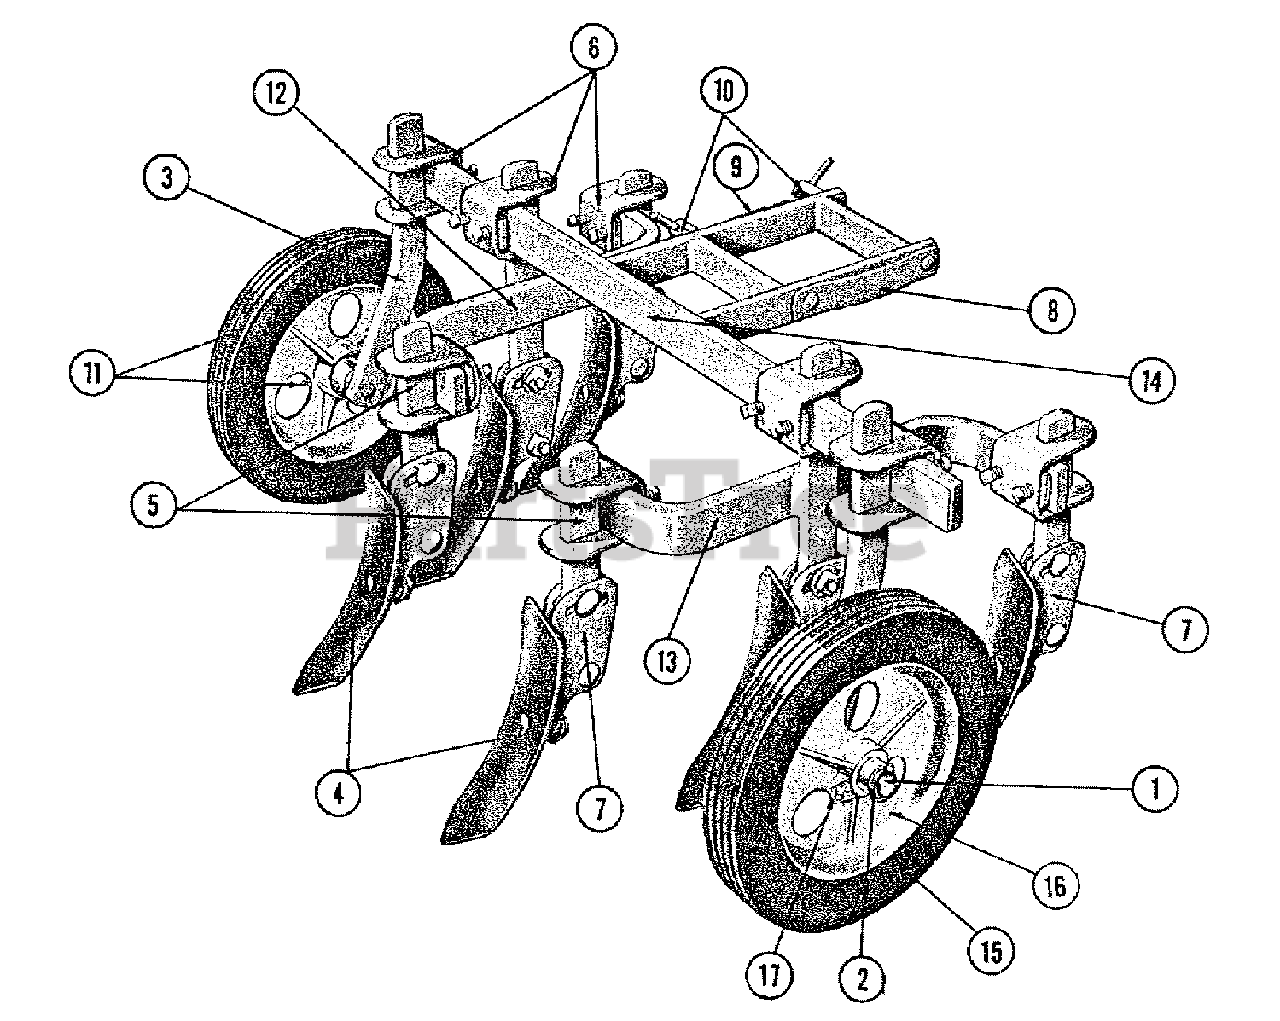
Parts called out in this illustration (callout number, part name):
1	GUAGE WHEEL SPINDLE
2	GUAGE WHEEL WASHER
3	GUAGE WHEEL STANDARD
4	CULTIVATOR STEEL w/BOLT
5	TOOL STANDARD
6	SHANK CLAMP
7	TOOL HOLDER ASSEMBLY
8	HITCH CLAMP ASSEMBLY
9	HITCH SIDE PLATE
10	WING NUT COMPLETE
11	WHEEL, Complete w/Juvenile Tires 10 x 1.75
12	RIGHT HAND TOOL FRAM ASSEMBLY
13	LEFT HAND TOOL FRAME ASSEMBLY
14	PUSH ARM ASSEMBLY
15	TIRE - 10 x 1.75
16	WHEEL ONLY
17	# 1641 GREASE FITTING
